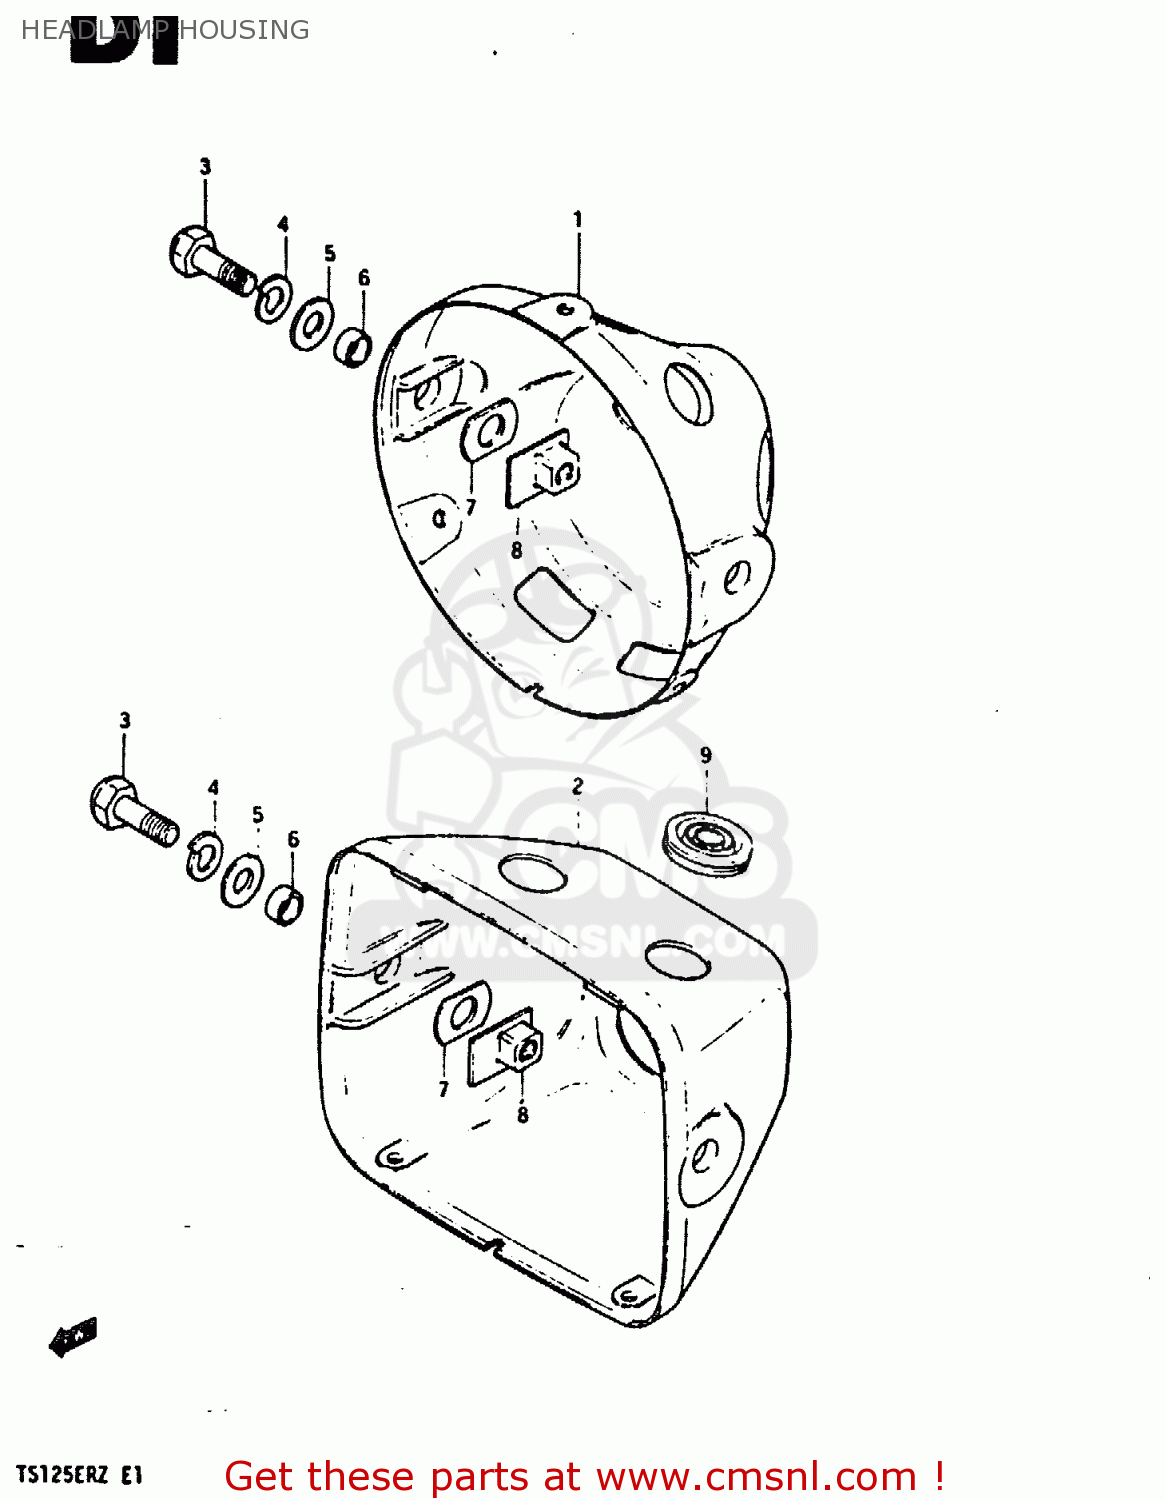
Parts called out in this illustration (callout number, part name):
1	HOUSING, HEADLAMP (BLACK)
3	BOLT
4	LOCK WASHER
5	WASHER
6	SPACER (8.8X12X7)
7	CUSHION
8	PLATE,HEADLAMP HOUSING
9	CUSHION
